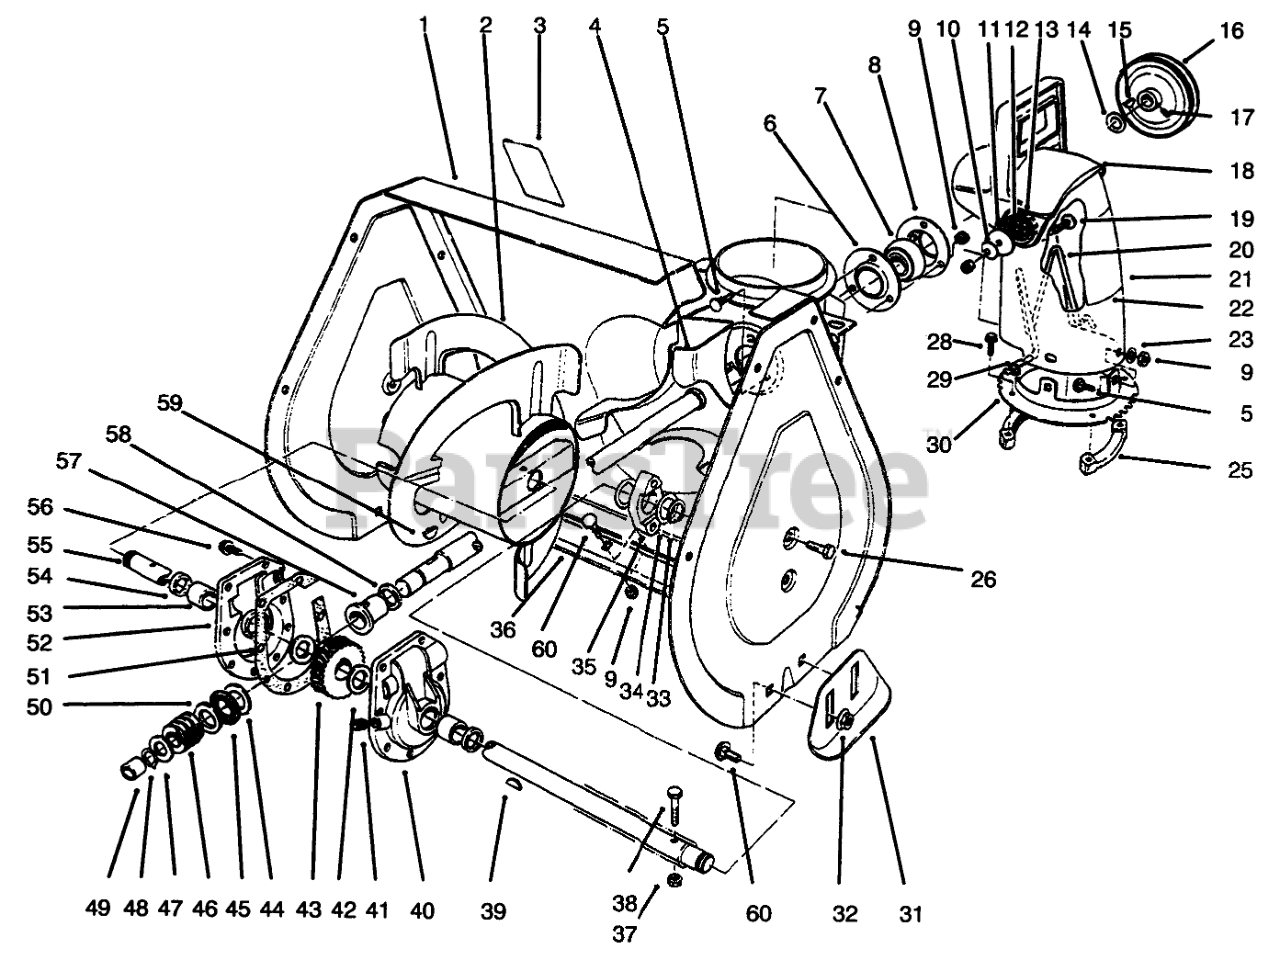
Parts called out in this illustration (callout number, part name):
1	Housing-Auger Model 38072 (Incl. Ref. #3)
2	Auger-R.H.
3	DECAL-WARNING, AUGER
4	Shaft & Impeiler
5	SCREW-CARR
6	Flange-Bearing Front
7	BEARING-BALL
8	Flange-Bearing Rear
9	NUT-LOCK, NI
10	WASHER-BELLEVILLE
11	WASHER-FLAT
12	PLATE-FRICTION
13	WASHER-RUBBER
14	WASHER
15	KEY-WOODRUFF
16	PULLEY
17	SCREW-SET, SQH
18	CHUTE-DEFLECTOR
19	SCREW-CARR
20	WIRE-CHUTE
21	Chute-Discharge Model 38072 (Incl. Ref. #22)
22	Decal-Danger
23	WASHER-PLAIN
25	RING-CHUTE, RETAINER
26	SCREW-HWHTF
28	SCREW-SPECIAL
29	NUT-PUSH
30	Chute Ring
31	Skid
32	NUT-HF
33	RING-RETAINING
34	WASHER
35	BEARING-AUGER
36	Blade-Scraper
37	NUT-LOCK, NI
38	SCREW-HH
39	KEY-WOODRUFF
40	Gear Case L.H. (Incl. Ref. #53 & 54)
41	PLUG-PIPE, SQH
42	WASHER-THRUST
43	GEAR-WORM, 27T
44	WASHER-THRUST
45	BEARING-THRUST
47	WASHER-THRUST
48	Ring-Snap
49	BUSHING
50	WASHER-THRUST
51	GASKET-CASE, GEAR
52	Gear Case R.H. (Incl. Ref. #53 & 54)
53	BUSHING
54	SEAL-OIL
55	SHAFT-AUGER
56	SCREW-TAPTITE
57	BUSHING-INPUT
58	RING-QUAD
59	KEY-WOODRUFF
60	BOLT-CARR
